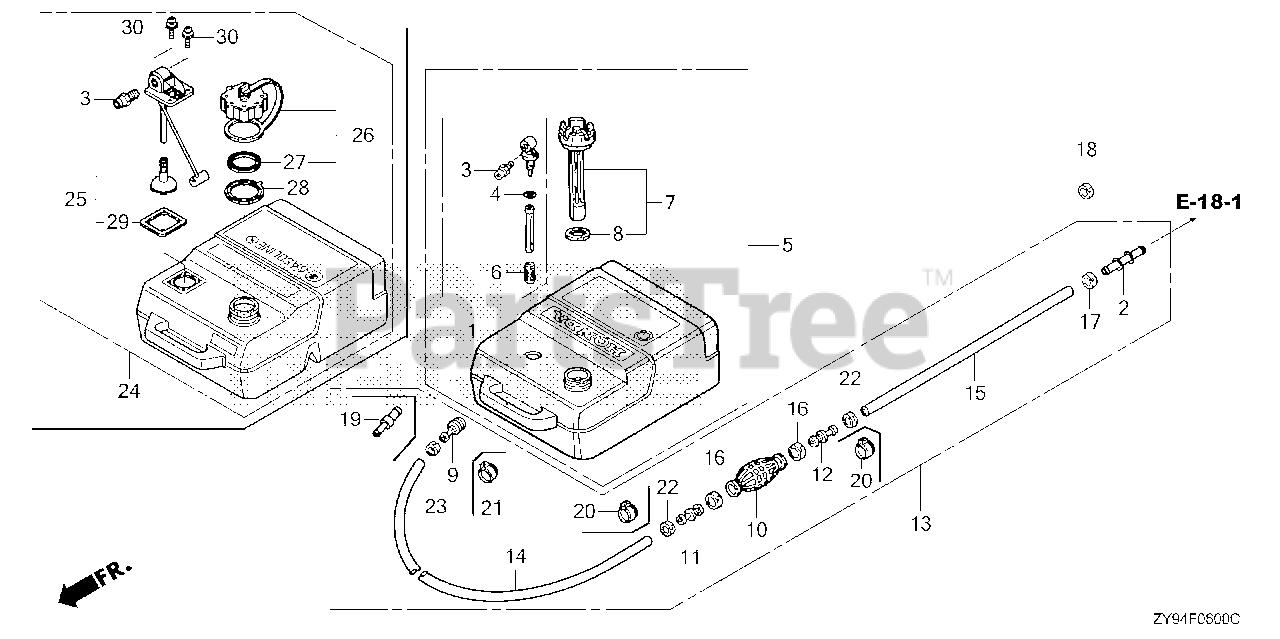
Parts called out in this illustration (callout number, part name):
1	JOINT ASSY., FUEL
2	JOINT, FUEL TUBE
3	FITTING, QUICK DISCONNECT
4	O-RING
5	TANK ASSY., FUEL
6	FILTER, FUEL
7	CAP, FUEL FILLER
8	GASKET, FUEL CAP
9	CONNECTOR, FUEL (CONNECTOR TYPE)
10	BULB, PRIMER
11	VALVE, IN.
12	VALVE, OUTLET
13	TUBE ASSY., FUEL TANK (JOINT TYPE)(FKM)
13	TUBE ASSY., FUEL (JOINT TYPE)
13	TUBE ASSY., FUEL TANK (CONNECTOR TYPE)
14	TUBE, FUEL LONG (7.3X2000) (CONNECTOR TYPE)
14	TUBE, FUEL LONG (7.3X2000)
14	TUBE, FUEL SHORT (6.3X500) (JOINT TYPE)
14	TUBE, FUEL SHORT (7.3X500) (JOINT TYPE)
14	TUBE, FUEL SHORT (JOINT TYPE)
15	TUBE, FUEL LONG (7.3X2000) (JOINT TYPE)
15	TUBE, FUEL SHORT (6.3X500) (CONNECTOR TYPE)
15	TUBE, FUEL SHORT (7.3X500) (CONNECTOR TYPE)
15	TUBE, FUEL SHORT (CONNECTOR TYPE)
16	BAND, TUBE CLIP (20MM)
17	BAND, TUBE CLIP (12.5MM)
18	BAND, TUBE CLIP (12.5MM)
19	JOINT, FUEL TUBE (JOINT TYPE)
20	CLAMP, FUEL TUBE
20	CLAMP, FUEL TUBE (14.0)
21	CLAMP, FUEL TUBE (CONNECTOR TYPE)
21	CLAMP, FUEL TUBE (14.0) (CONNECTOR TYPE)
22	BAND, TUBE CLIP (12.5MM)
23	BAND, TUBE CLIP (12.5MM)
24	TANK ASSY., FUEL
25	FILTER KIT, FUEL
26	CAP, FUEL FILLER
27	GASKET, FUEL CAP
28	RETAINER, PRESSURE RELIEF
29	GASKET, FUEL PICK-UP
30	BOLT-WASHER (5MM) (SEAL)
